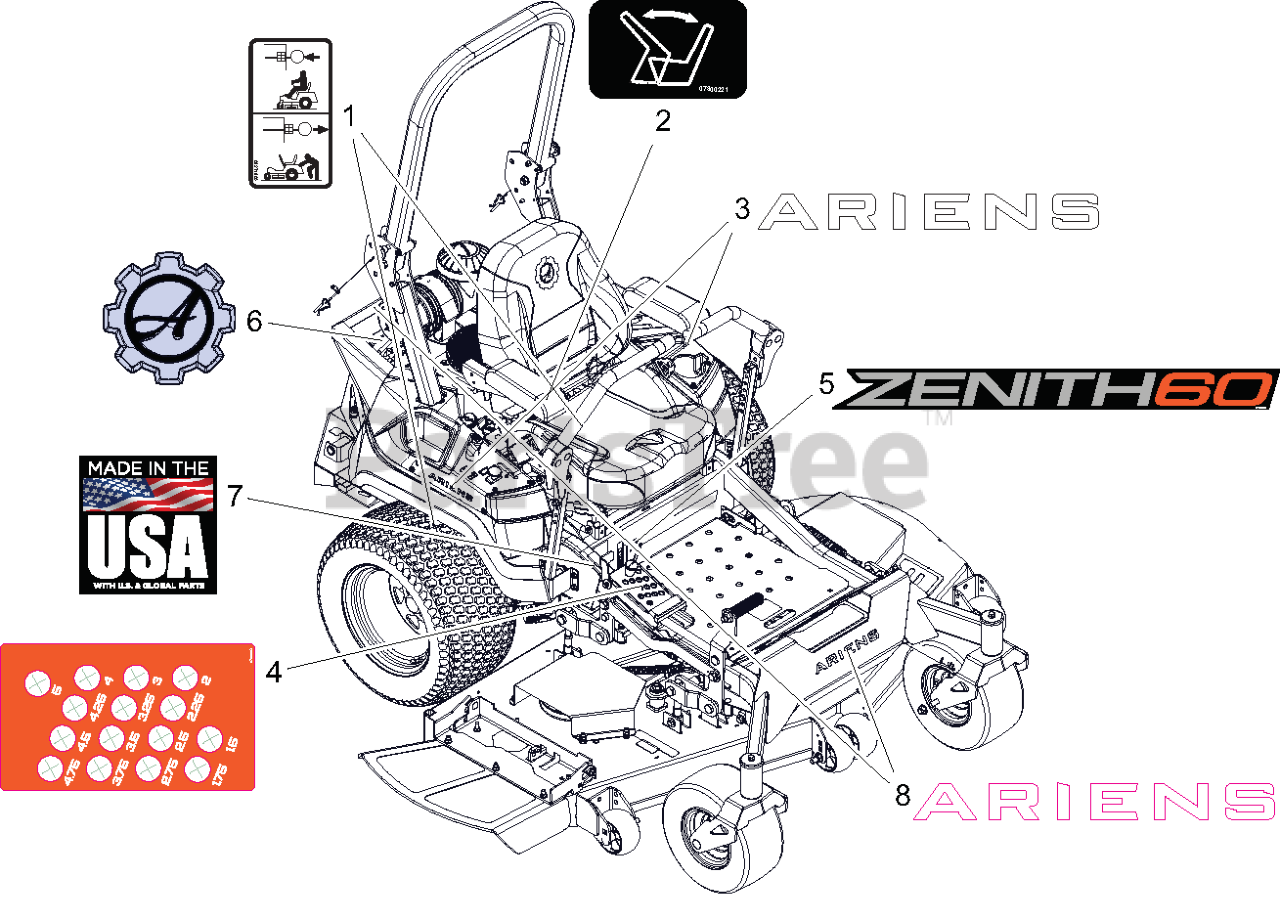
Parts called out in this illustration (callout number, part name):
1	DECAL, TRANSMISSION DISCONNECT
2	DECAL - SEAT RELEASE
3	DECAL, ARIENS (6.50")
4	DECAL, ARIENS HOC
5	DECAL, ZENITH 60
6	DECAL, ARIENS - GEAR BADGE
7	DECAL, MADE IN USA
8	DECAL - ARIENS 9.625"
